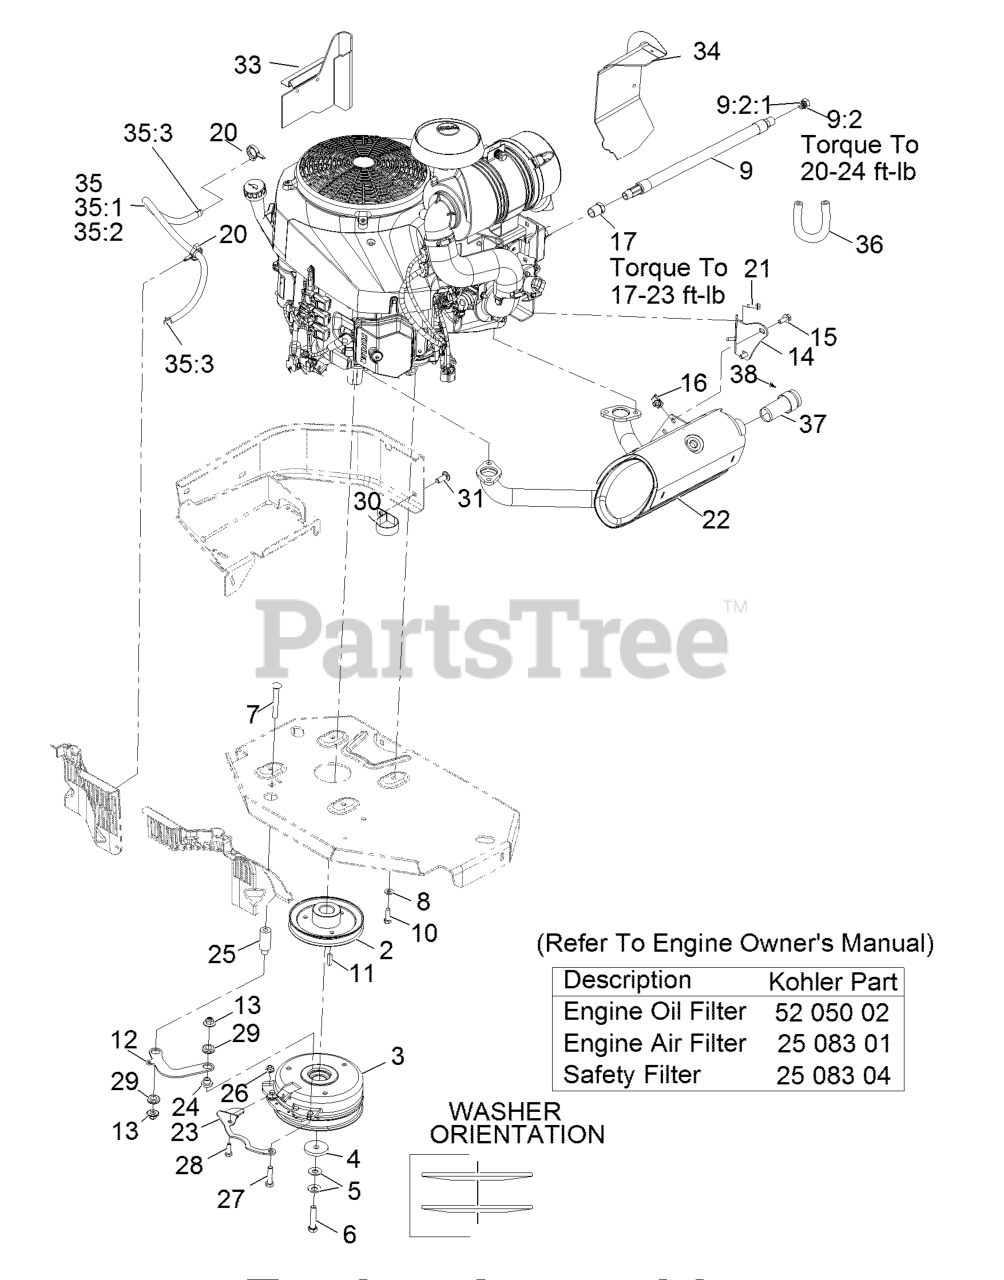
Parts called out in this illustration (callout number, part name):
2	SHEAVE
4	WASHER-CLUTCH
5	WASHER-SPRING
6	SCREW-HH W/LOCTITE
7	SCREW-CARR
8	WASHER-SPRING
9	OIL DRAIN HOSE ASM
9:2	PLUG-HH
9:2:1	O-RING
10	SCREW-HH
12	LINK-ANCHOR, CLUTCH
13	Nut-Nyloc 3/8-16 Flg
14	BRACKET-MUFFLER
15	SCREW-HHF
17	BUSHING
20	CLAMP-HOSE
23	BELT-GUIDE
26	NUT-HF, NI
27	SCREW-HH
28	SCREW-HH
29	GROMMET-RUBBER
30	CLAMP-R
31	SCREW-CARR
33	BAFFLE-RH
35	FUEL LINE ASM
35:1	HOSE-FUEL
35:2	SLEEVE, THERMAL
35:3	CLAMP-HOSE
36	SLEEVE, THERMAL-SHORT
37	ARRESTOR-SPARK
38	SCREW-HWH
